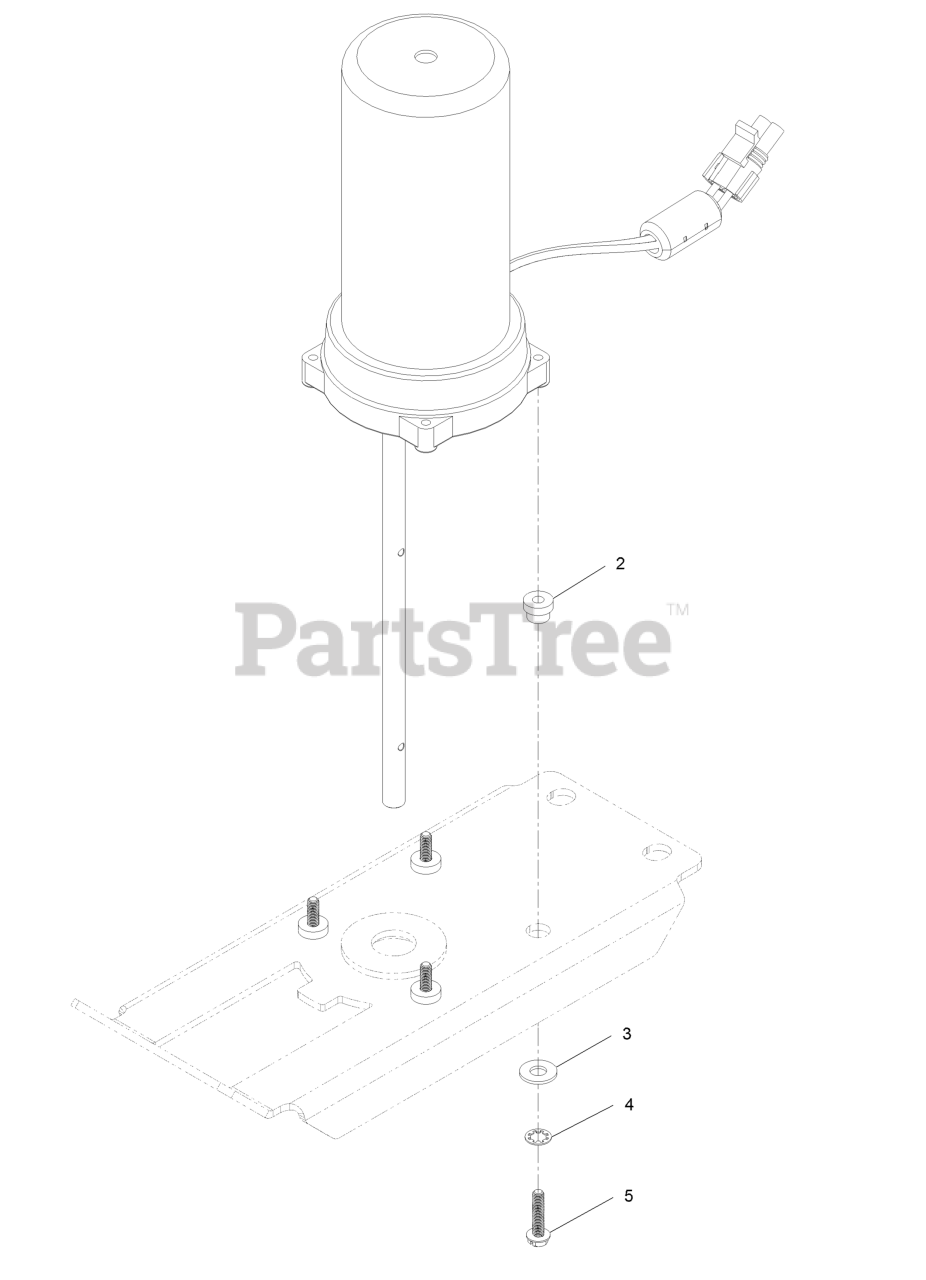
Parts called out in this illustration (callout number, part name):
2	Spacer-Flanged
3	Washer-Flat
4	Washer-Lock, Int
5	Screw-SHWH
